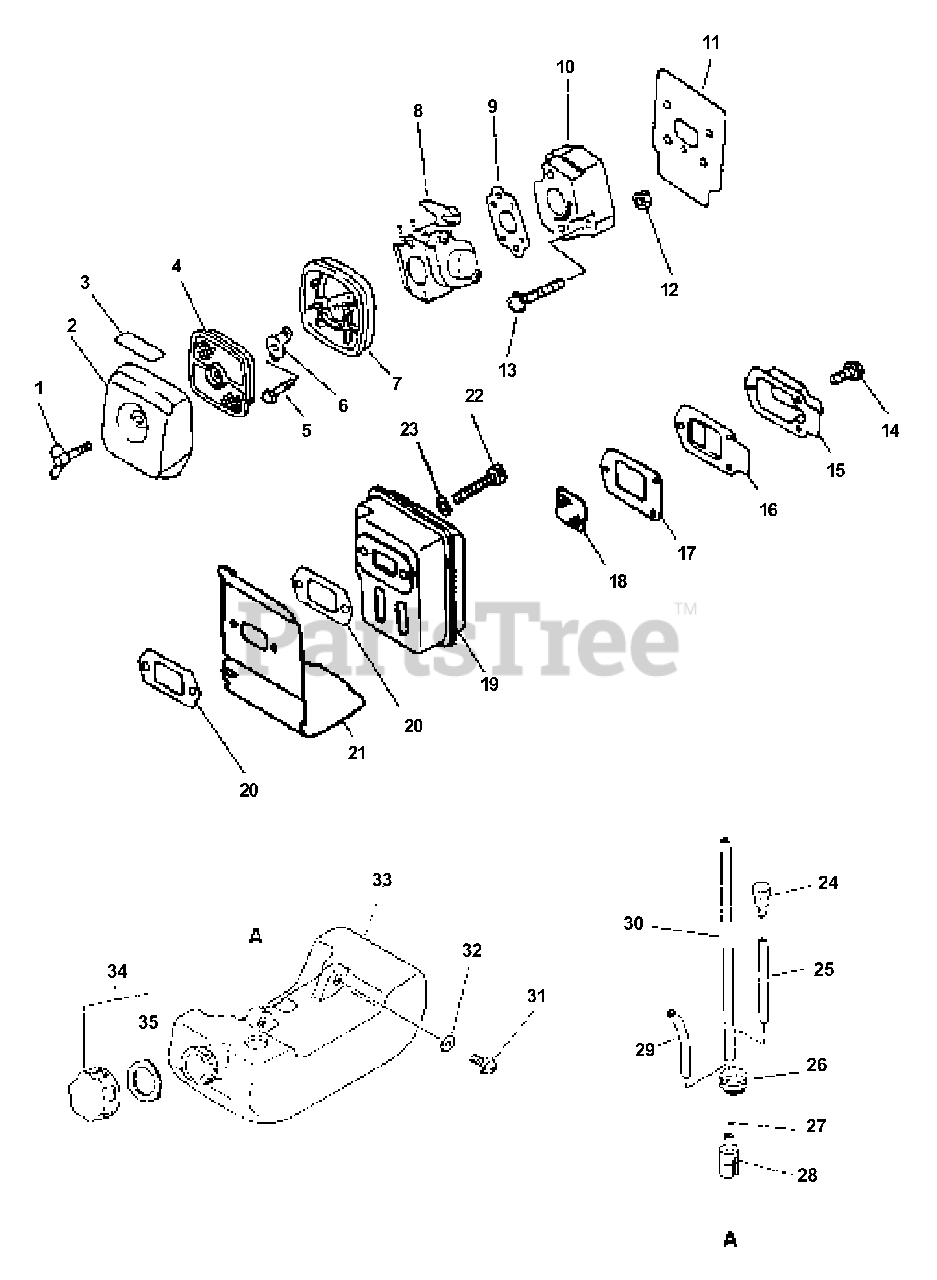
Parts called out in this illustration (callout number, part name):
1	THUMBSCREW
2	COVER, AIR FILTER - GRAY
3	LABEL - CHOKE
4	FILTER, AIR - SINGLE LAYER
5	SCREW - 5X65
6	PLATE, PREVENT
7	AIR FILTER CASE ASSY
8	CARBURETOR C1U-K52
9	GASKET, INTAKE
10	INSULATOR, INTAKE
11	SHIELD, INTAKE
13	SCREW - 5X20
14	SCREW - 4X10
15	GUIDE, EXHAUST - OUTER
16	GASKET, EXHAUST - INNER
17	GASKET, EXHAUST
18	SCREEN, SPARK ARRESTOR
20	GASKET, EXHAUST
21	COVER, EXHAUST
22	SCREW - 5X55
23	WASHER - 5
24	VENT, FUEL TANK
25	PIPE - 3X5X70 -- BLACK
26	GROMMET
27	CLIP - 6
28	FILTER, FUEL
29	PIPE - 3X6X90 -- CLEAR
30	PIPE - 3X5X180 -- BLACK
31	SCREW - 5X16
32	WASHER - 5
33	FUEL TANK ASSY
34	CAP ASSY
35	GASKET, CAP
